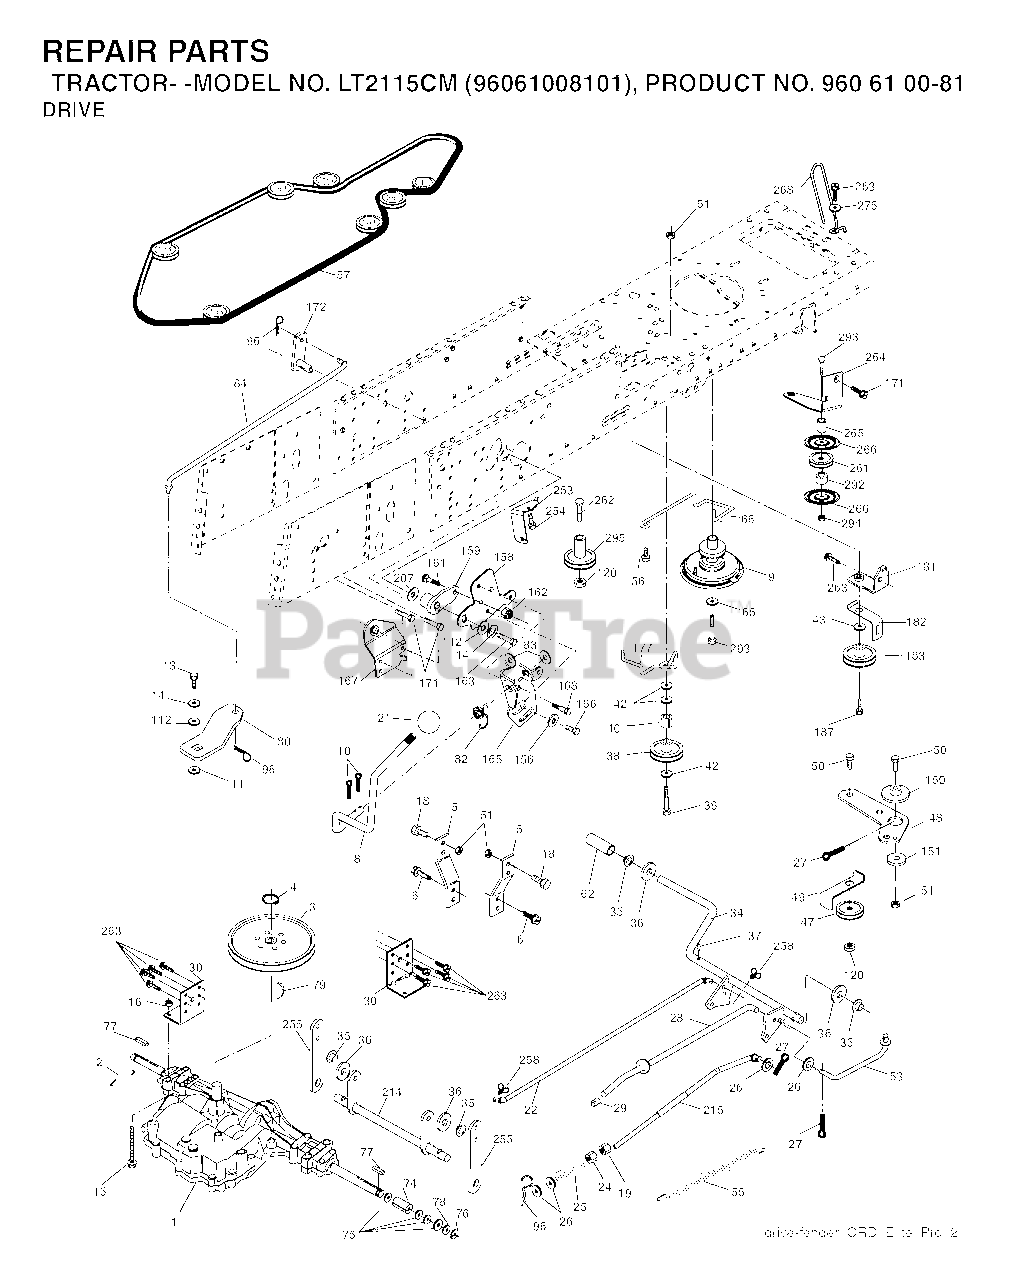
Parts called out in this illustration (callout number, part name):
2	SPRING,BRAKE RETURN
4	RETAINING RING LT
5	STRAP TORQUE
6	SCREW 5/16"
8	ROD SHIFT FENDER ADJUST LT
10	PIN COTTER
11	WASH-SHFT PLT LT
13	BOLT 1/4-28X3/4
14	LOCKWASHER
15	BOLT HEX 5/16-18 GR 5
16	NUT.71038.31-18.HEX.NYLOCK
19	NUT
21	KNOB.DUCKHEAD.1/2
24	NUT
25	SPRING ROD LT
27	COTTER PIN
28	ROD, PARKING BRAKE
29	PLUNGER CAP
30	BRKT, MOUNT TRNSAXLE
34	SHAFT, FOOT PEDAL
35	BEARING.NYLON
36	WASHER LT
37	DRIVE PIN
38	PULLEY.FLAT
42	WASHER
47	IDLER PULLEY
48	BELLCRANK, CLUTCH
49	RETAIN BELT
50	BOLT.3/8-16X1.50
51	LOCKNUT
53	LINK.CLUTCH.7.66.2005
55	SPRING, RETURN LT
56	SCREW.3/8-16
57	V-BELT.KEV.111"
62	COVER, PEDAL
65	LOCKWASHER
66	KEEPER BELT ENGINE
74	SPACER AXLE
76	E-RING LT
77	SQUARE KEY
80	ARM SHIFT
82	SHIFT SPRING
83	WASHER
96	RETAINER M
112	WASHER LT
120	NUT LOCK FLG 3/8-16 UNC
150	BUSHING.BELLCRANK.GRD.DR
151	WASHER 12/32X2X10GA
156	WASHER.SRRTD.5/16
158	BRACKET
159	HUB.SHIFT
161	BOLT
162	NUT.CROWNLOCK.1/4
165	RP BRACKET
167	BRACKET
168	BOLT.SHOULDER.5/16-18X
187	BOLT.5/16-18X1.25
207	WASHER NYL
254	SCREW 3/8-16X1
258	CLIP RETAINER
261	FLAT IDLER PULLEY
263	SCREW, 3/8-16X3/4
265	SPACER IDLER
275	WASHER
294	NUT, HEX 3/8-16
295	PULLEY IDLER COMPOSITE
